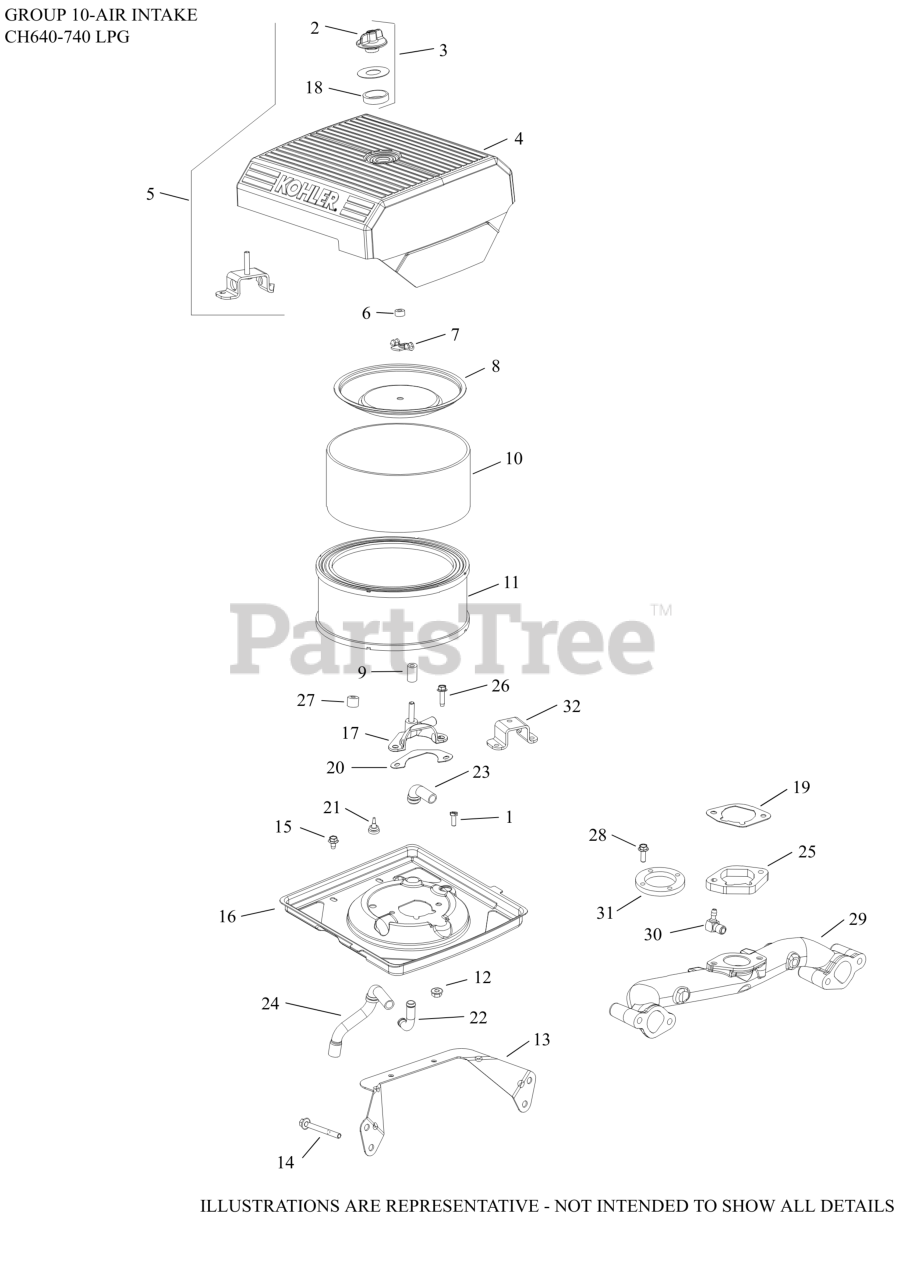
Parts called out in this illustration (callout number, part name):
2	KNOB, COVER
3	KIT, KNOB W/SEAL
4	COVER, AIR CLEANER
5	KIT, AIR CLEANER COVER
6	SEAL, INNER AIR CLEANER
7	NUT, WING
8	COVER, INNER AIR CLEANER
10	PRE CLEANER LOW ELEMENT
11	ELEMENT, AIR CLEANER
12	NUT, FLG M6X1.0
13	AIR CLEANER BRACKET
16	KIT, AIR CLEANER BASE
17	CUP, FUEL SPITBACK W/NIPPLE
19	GASKET, AIR CLEANER BASE
20	GASKET, FUEL SPITBACK CUP
21	PLUG, HOLE
23	HOSE, BREATHER
24	HOSE, BREATHER
25	SPACER, AIR CLEANER BASE
26	SCREW, THD FRM-USE 25 086 473-S
NI	O-RING, INTAKE PORT (PIM)
NI	KIT, INTAKE MANIFOLD-(#24164277S)
